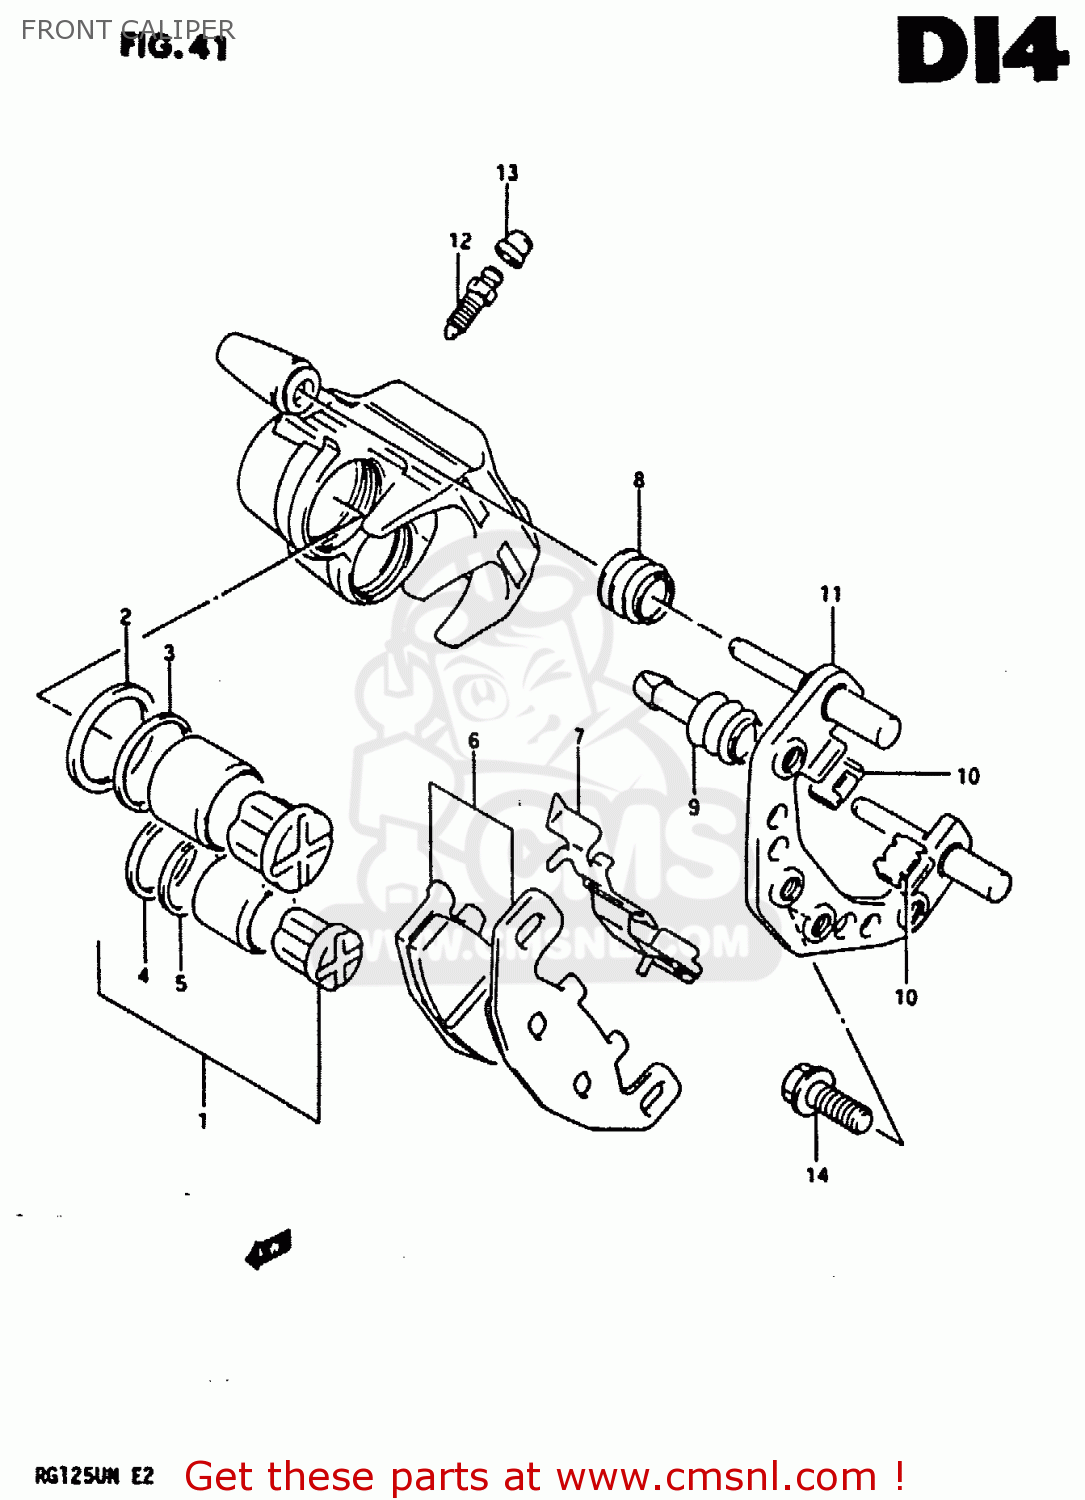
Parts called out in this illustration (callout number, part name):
1	PISTON SET
2	SEAL,PISTON
3	SEAL,WIPER
4	SEAL,PISTON
5	SEAL,WIPER
6	PAD SET (NAS)
7	SPRING,PAD
8	BOOT,AXLE
9	INSULATOR,AXLE
10	GUIDE,PAD
11	CARRIER,CALIPER
12	BLEEDER
13	CAP,BREATHER
14	BOLT
